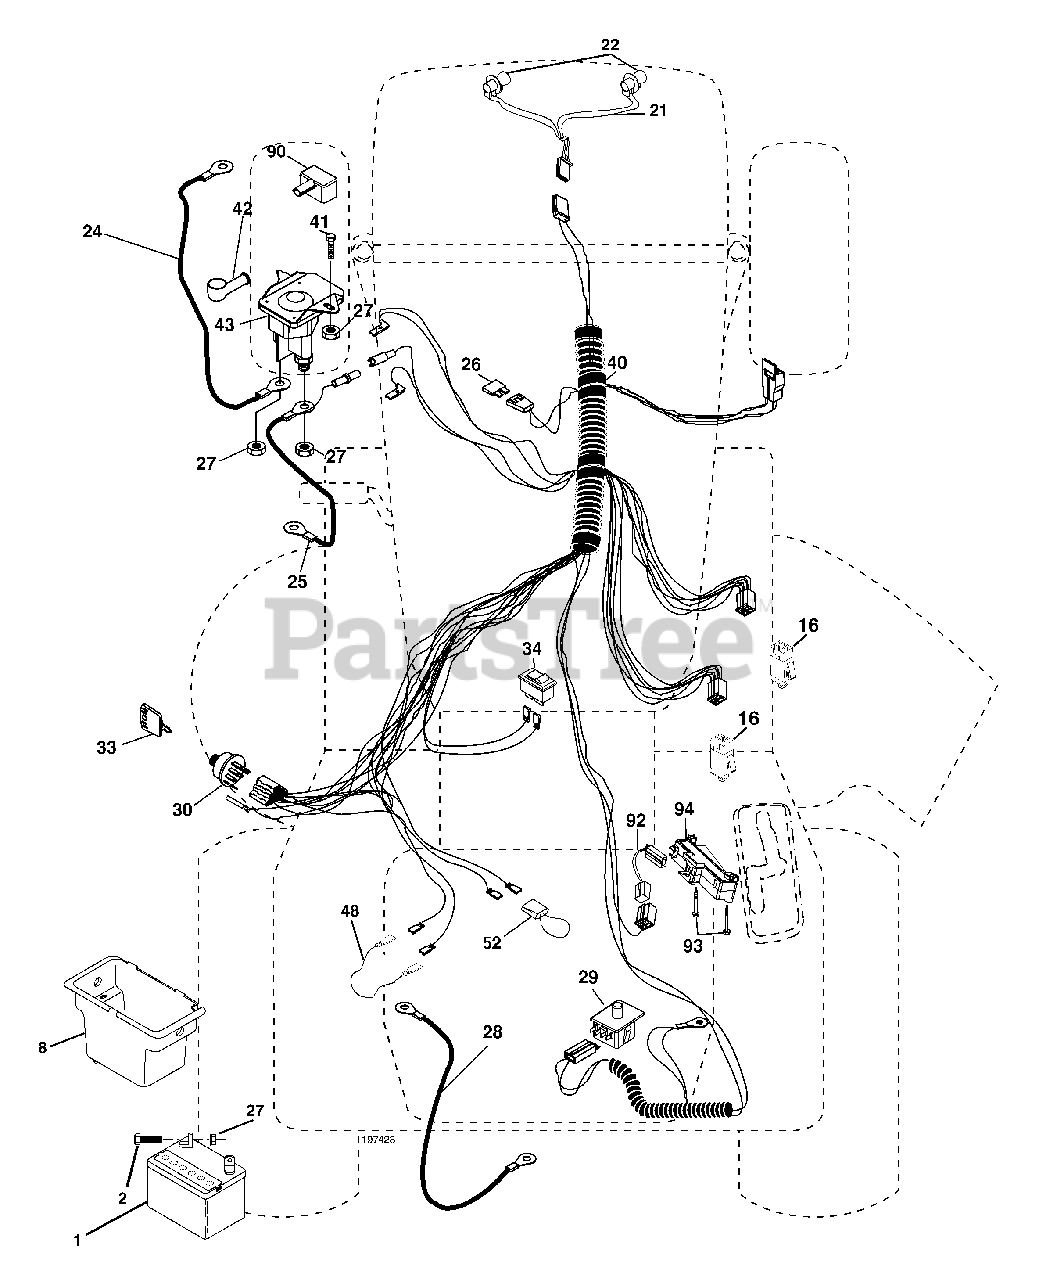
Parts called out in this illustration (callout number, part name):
1	Battery
2	Bolt Hex Hd 1/4-20 unc x 3/4
8	Box Battery
16	Switch Interlock
21	Harness Socket Light
22	Bulb, Light # 1156
24	Cable Battery
25	Cable Battery 6 Ga. Red w/16 wire 44"
27	Nut Keps Hex 1/4-20 unc
28	Cable Ground 12" Blk 6 Ga.
29	Switch Seat
30	Switch Ign
33	Key Ign Molded Generic
34	Switch Light/Reset
40	Harness Ign
41	Bolt Fin Hex 1/4-20 unc x 1/2
42	Cover Terminal Red
43	Solenoid
48	Adapter Ammeter
52	Hourmeter Adapter
90	Cover Terminal
92	Harness Pigtail Console
93	Screw Plastite 10-14 x 2.0
94	Module Revers ROS
